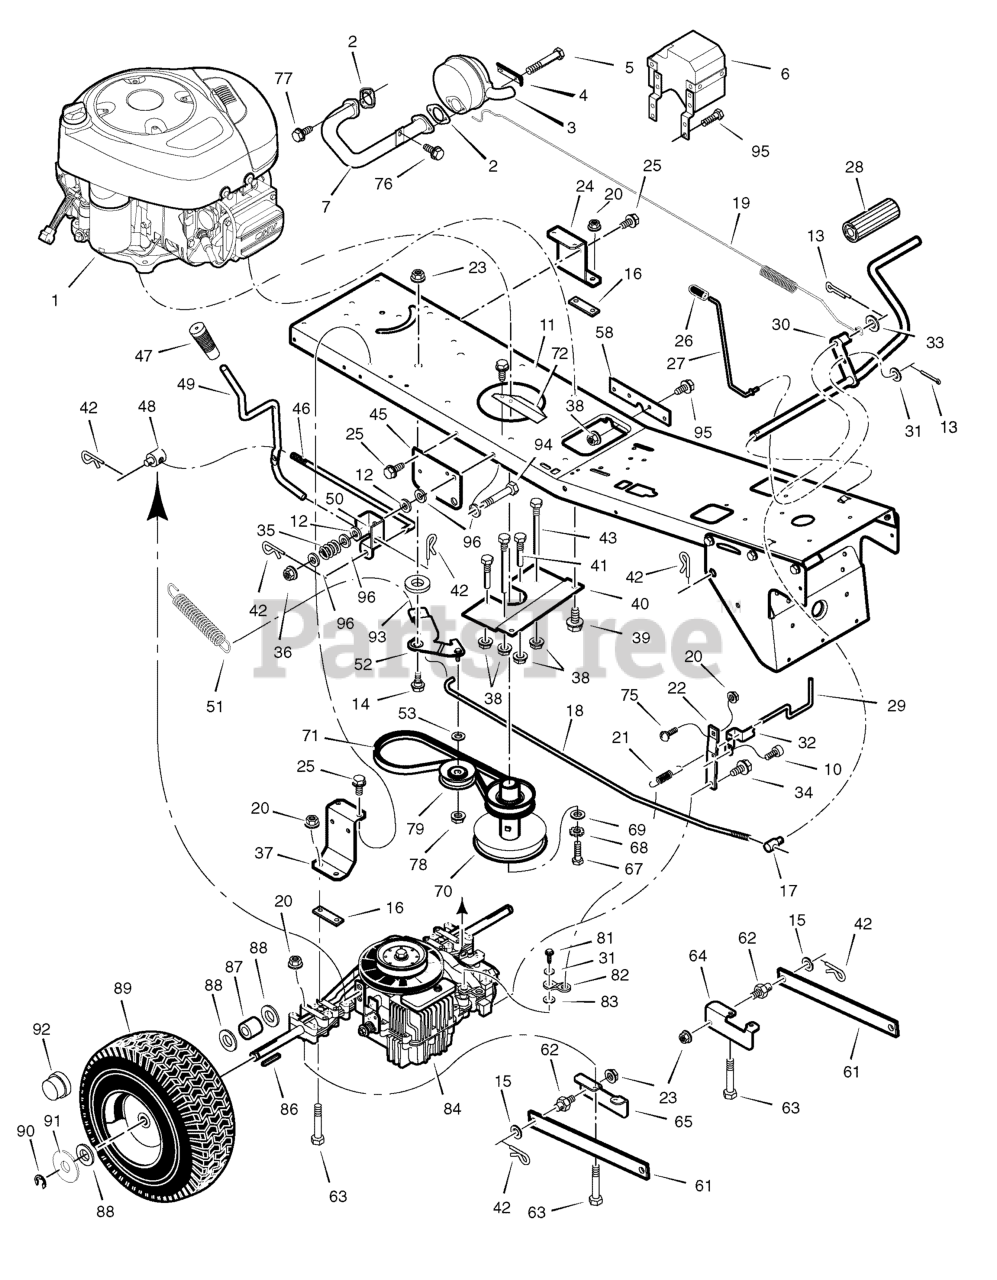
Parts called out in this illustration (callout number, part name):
1	Engine
2	GASKET, Exhaust
4	Lock, Muffler Screw
5	Bolt, Hex
6	Shield, Heat
7	Tube, Exhaust
10	Screw
13	Pin, Cotter
14	Bolt, Shoulder
16	Plate, Transaxle
17	Nut, Adjusting
18	Rod, Clutch Hydro
19	Spring, Brake
20	Nut
21	Spring, Roll Release
22	Bracket, Torque
23	Nut
24	Bracket, Left Transaxle
27	Rod, Parking Brake
28	Pedal
29	Rod, Roll Release
30	Rod, Clutch/Brake
32	Bracket, Roll Release
33	Washer
35	Spring, Compression
37	Bracket, Right Transaxle
38	Nut
39	Screw
40	Plate, Belt Guide
41	Guide, Belt -Long
42	Pin, Hair
43	Guide, Belt -Short
45	Bracket, Lift Pivot
46	Rod, Shift Link
48	Nut, Adjusting
49	Lever, Shift
50	Bracket, Pivot
51	Spring - Variator Drive
52	Arm, Idler
58	Plate, Reinforcement
62	Pin, Threaded
63	Bolt, Hex
64	Bracket, Left Rear Hanger
65	Bracket, Right Rear Hanger
67	Bolt, Hex
68	Lockwasher
70	Pulley Stack
71	Belt, Drive
72	Heat Shield
75	Bolt, Carriage
78	Locknut
79	Pulley, Idler
81	Cap Screw
82	Arm, Disconnect
84	Transaxle **
86	Key, Square
87	SPACER, Rear Wheel
89	Wheel & Tire Assembly
92	Hub Cap
93	Washer
94	Bolt, Hex
96	Washer
